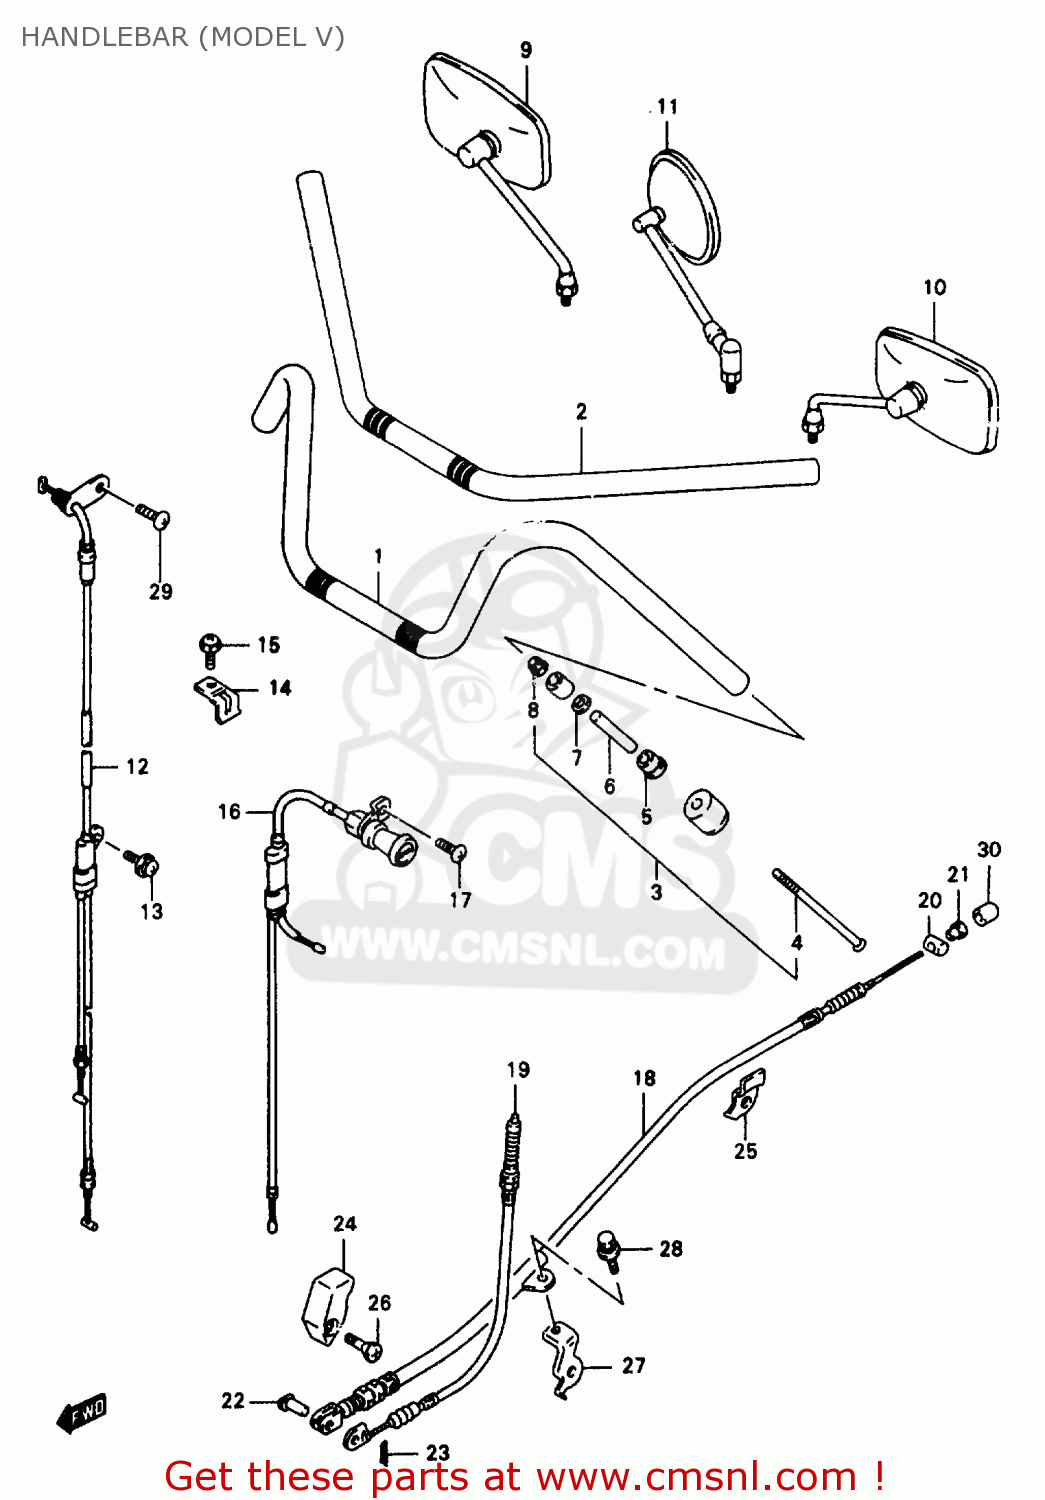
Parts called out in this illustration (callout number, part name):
1	HANDLEBAR
2	HANDLEBAR
3	BALANCER SET, HANDLEBAR
4	SCREW(6X110)
5	EXPANDER,HANDLE BALANCER NO.2
6	SPACER,EXPANDER
7	WASHER(6.5X18X1)
8	NUT
9	MIRROR ASSY,RR VIEW,R
10	MIRROR ASSY,RR VIEW,L
11	MIRROR ASSY,RH
12	CABLE ASSY,THROTTLE
13	SCREW
14	CLAMP,THROTTLE CABLE
15	SCREW
16	CABLE ASSEMBLY,STARTER
17	SCREW 6X10
18	CABLE,RR BRAKE
19	CABLE,STOP LAMP SWITCH
20	PIN(13X18)
21	NUT
22	PIN(L:17.5)
23	PIN
24	GUIDE,RR BRAKE CABLE
25	CLAMP,RR BRAKE CABLE
26	SCREW
27	BRACKET,RR BRAKE CABLE
28	BOLT
29	SCREW
30	CAP,GREASE NIPPLE
31	BOLT
32	SCREW
33	CAP,GREASE NIPPLE
